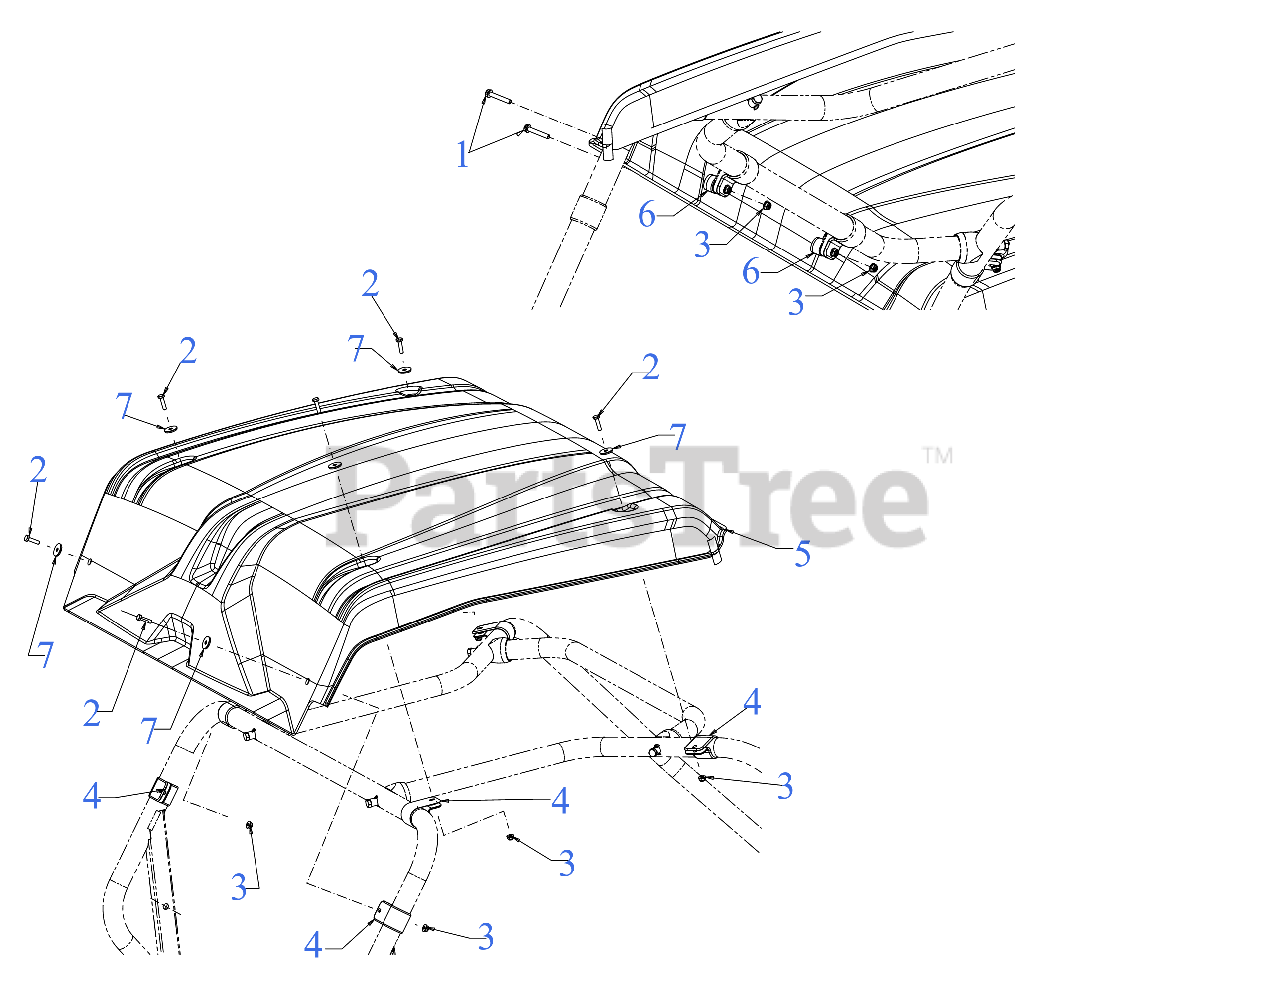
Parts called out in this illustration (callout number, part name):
1	HEX FLANGE BOLT 1/4-20 x 1.5
2	SCREW 1/4-20 X1.00 GR5
3	FLANGE LOCK NUT
7	FLAT WASHER .275 x 1.00 x .103
